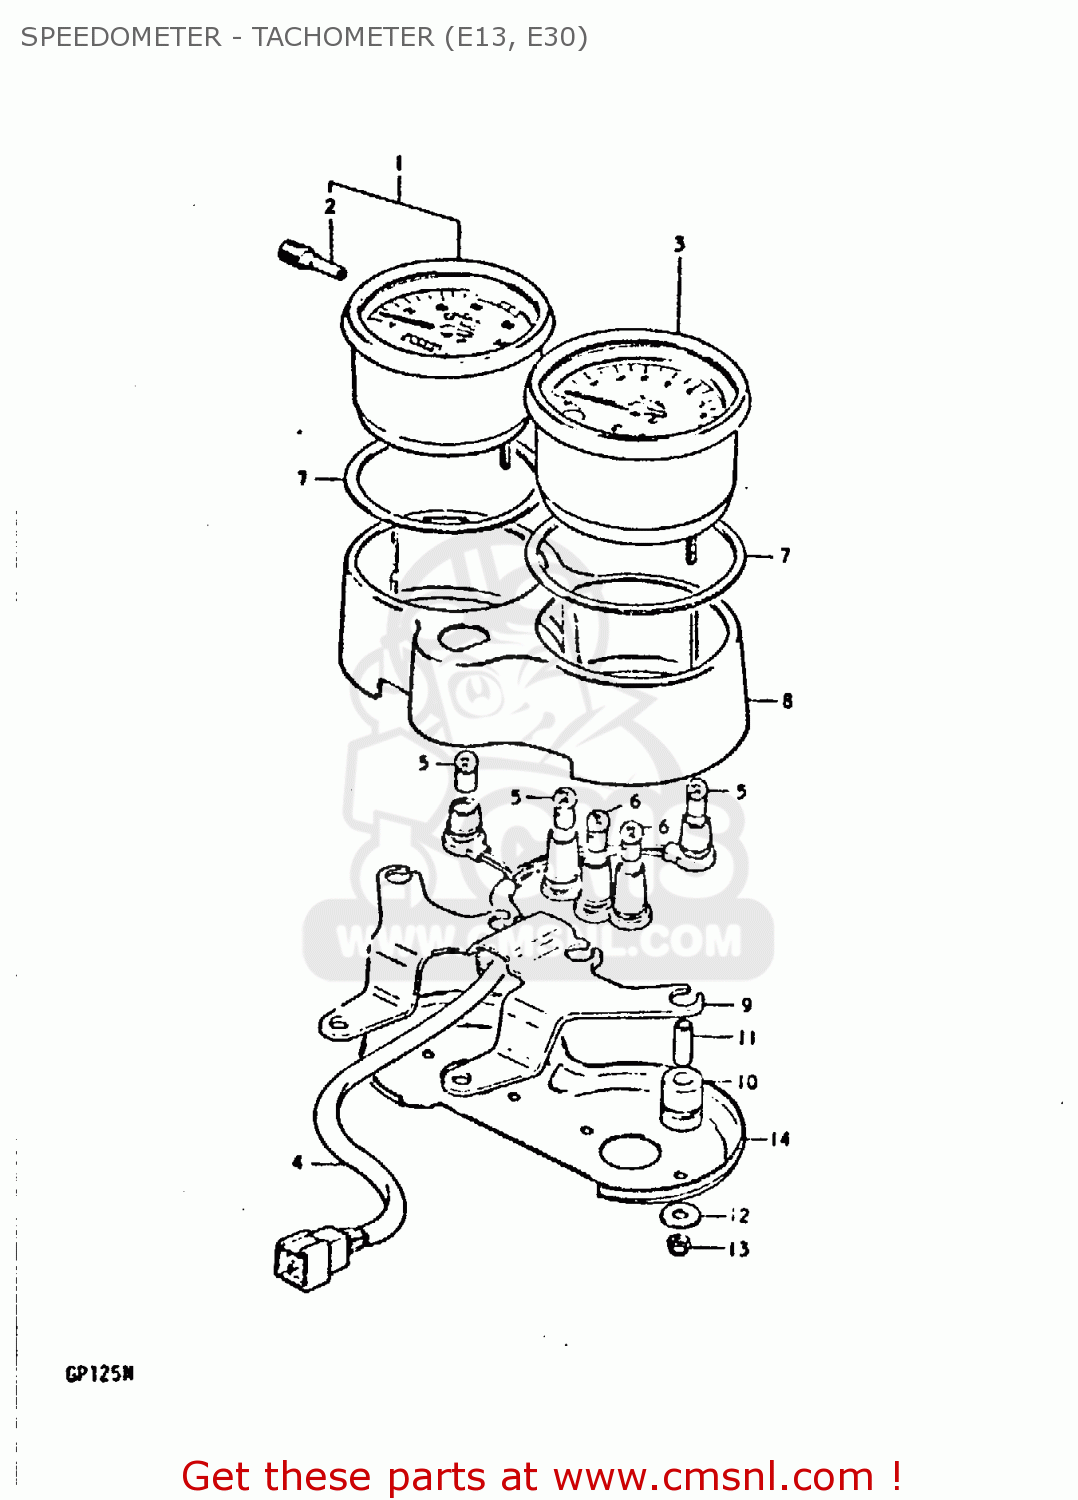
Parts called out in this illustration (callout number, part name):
1	SPEEDOMETER (KILO)
2	KNOB,TRIP METER
3	TACHOMETER ASSY
4	SOCKET
5	BULB(6V1.7W,STANLEY,A61A)
6	BULB(6V/3W)
7	GASKET, METER
8	CASE, METER
9	BRACKET
10	CUSHION
11	SPACER
12	WASHER,METER
13	NUT
14	UNDER PLATE
